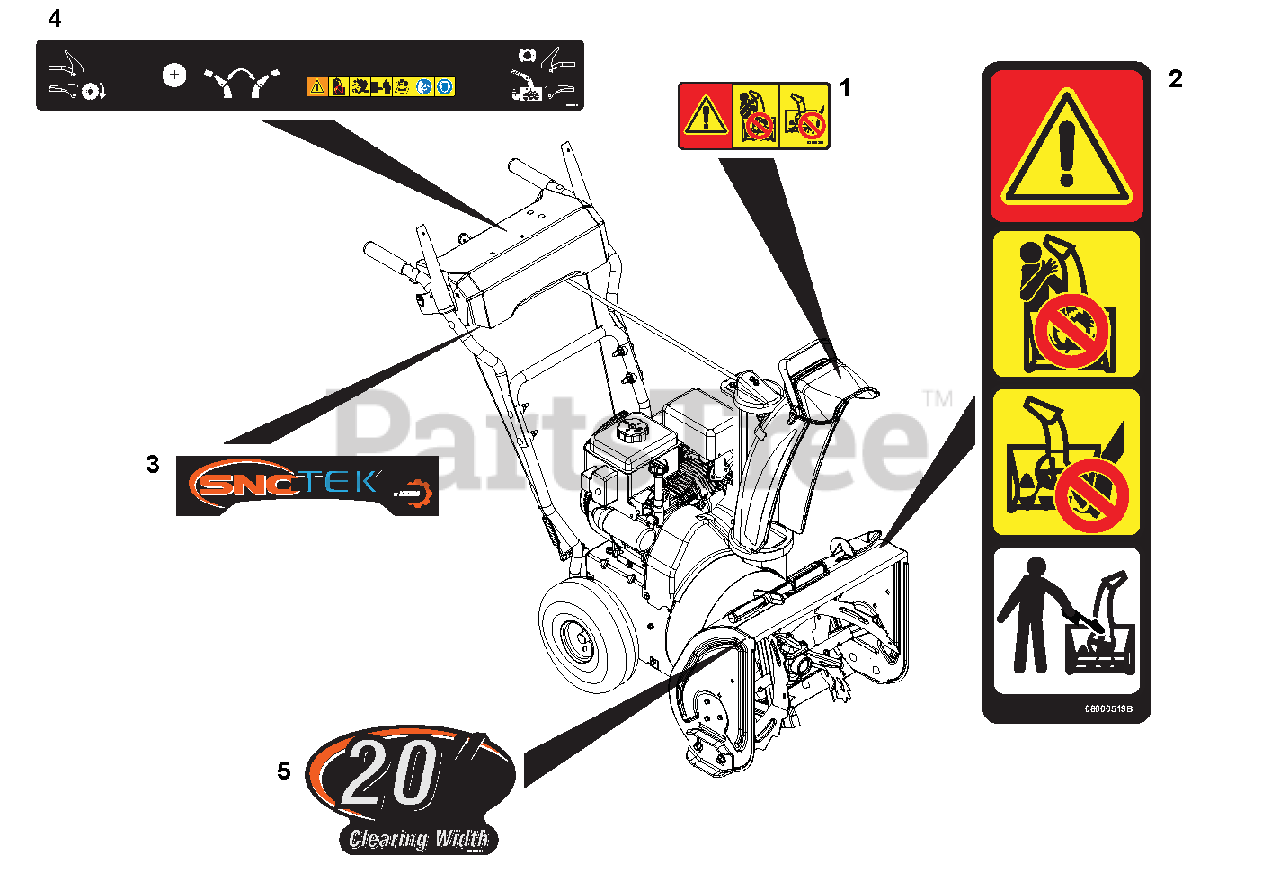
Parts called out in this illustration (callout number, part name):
1	DECAL, DANGER SNO-TEK
2	DECAL, DANGER - ROTATING PARTS
3	DECAL, DASH - SNO-TEK
4	DECAL, CONTROL - SINGLE SPEED
5	DECAL, HOUSING SNO-TEK 20
